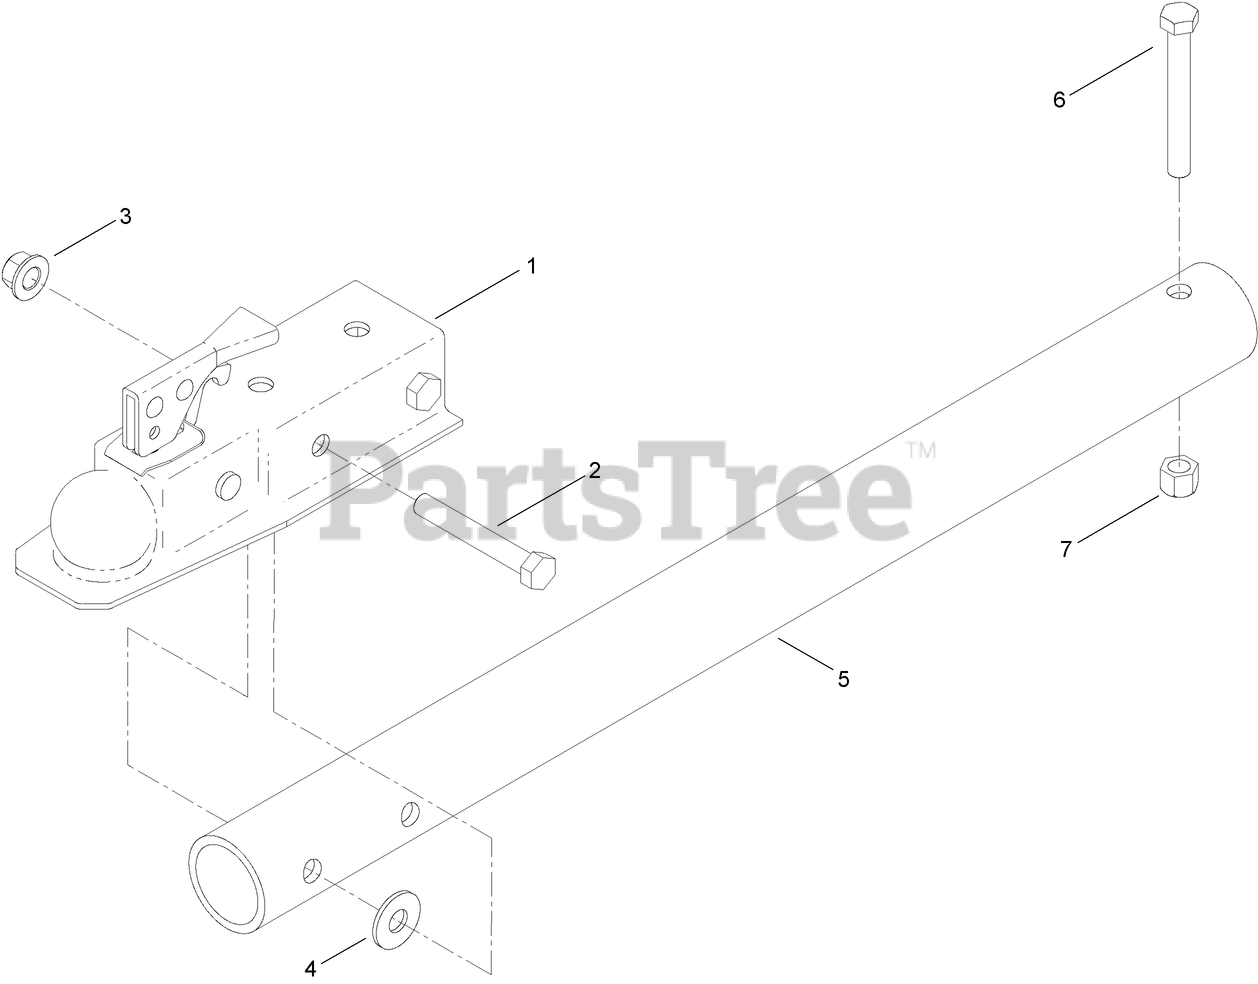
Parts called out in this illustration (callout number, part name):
1	COUPLER-BALL 2IN ZINC
2	SCREW-HH
3	NUT-LOCK
4	WASHER-FLAT
5	PIPE-TOW POLE
6	SCREW-HH
7	NUT-LOCK, NI
